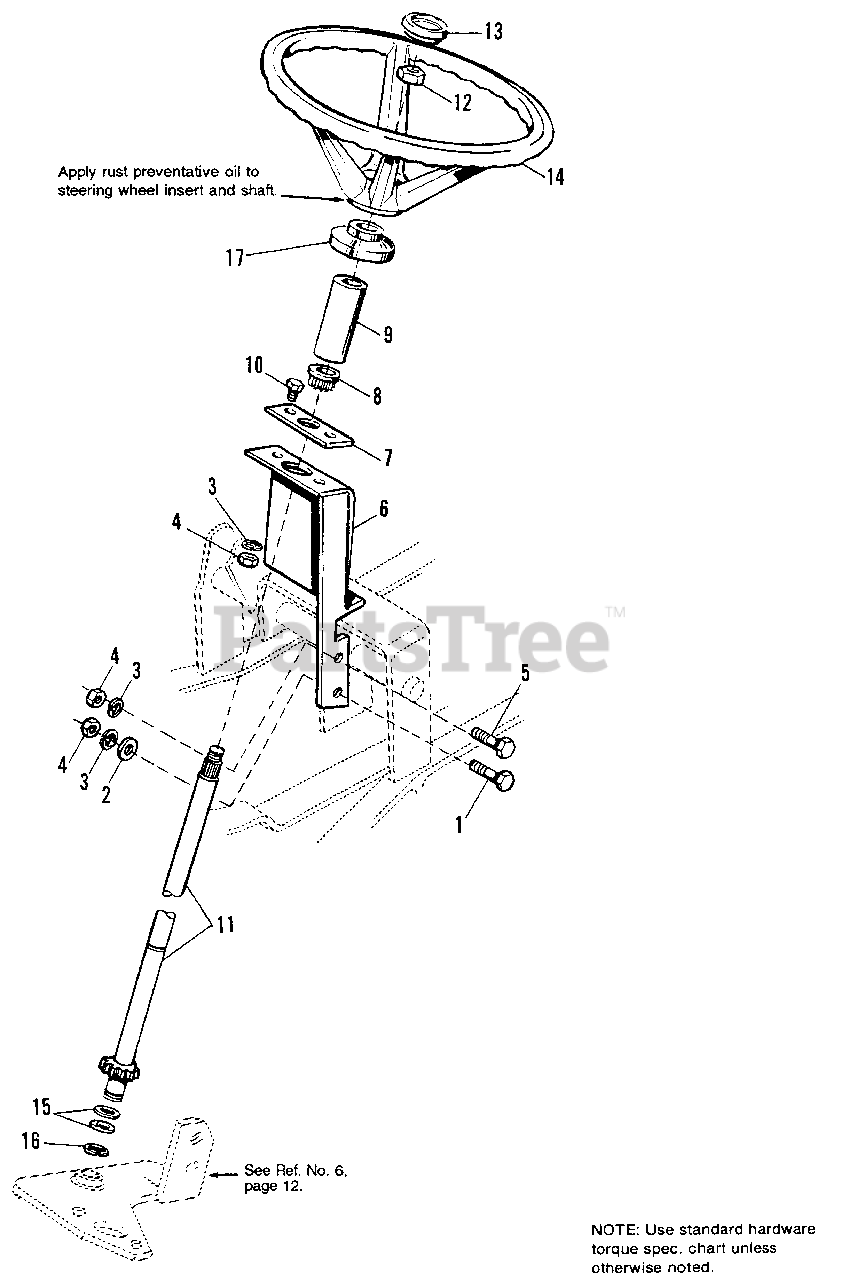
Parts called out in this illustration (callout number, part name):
1	CAPSCREW, Hex Hd., 3/8-16 x 1-1/4
2	WASHER, Plain, 13/32
3	LOCKWASHER 3/8
4	NUT, Hex, 3/8-16
5	CAPSCREW, Hex Hd., 3/8-16 x 1
6	BRACKET ASSY., Steering
7	PLATE, Steering
8	BUSHING, Steering
9	TUBE, Steering Hub
10	CAPSCREW, Hex Hd., 5/16-18 x 1
11	SHAFT & COUPLING ASSY.
12	NUT, Hex, Jam, 5/8-18
13	CAP, Steering Wheel
14	WHEEL ASSY., Steering
15	WASHER, Thrust, 49/64 x 1-3/8 x 1/16
16	RING, Retaining 3/8
17	BOOT, Steering Stem
